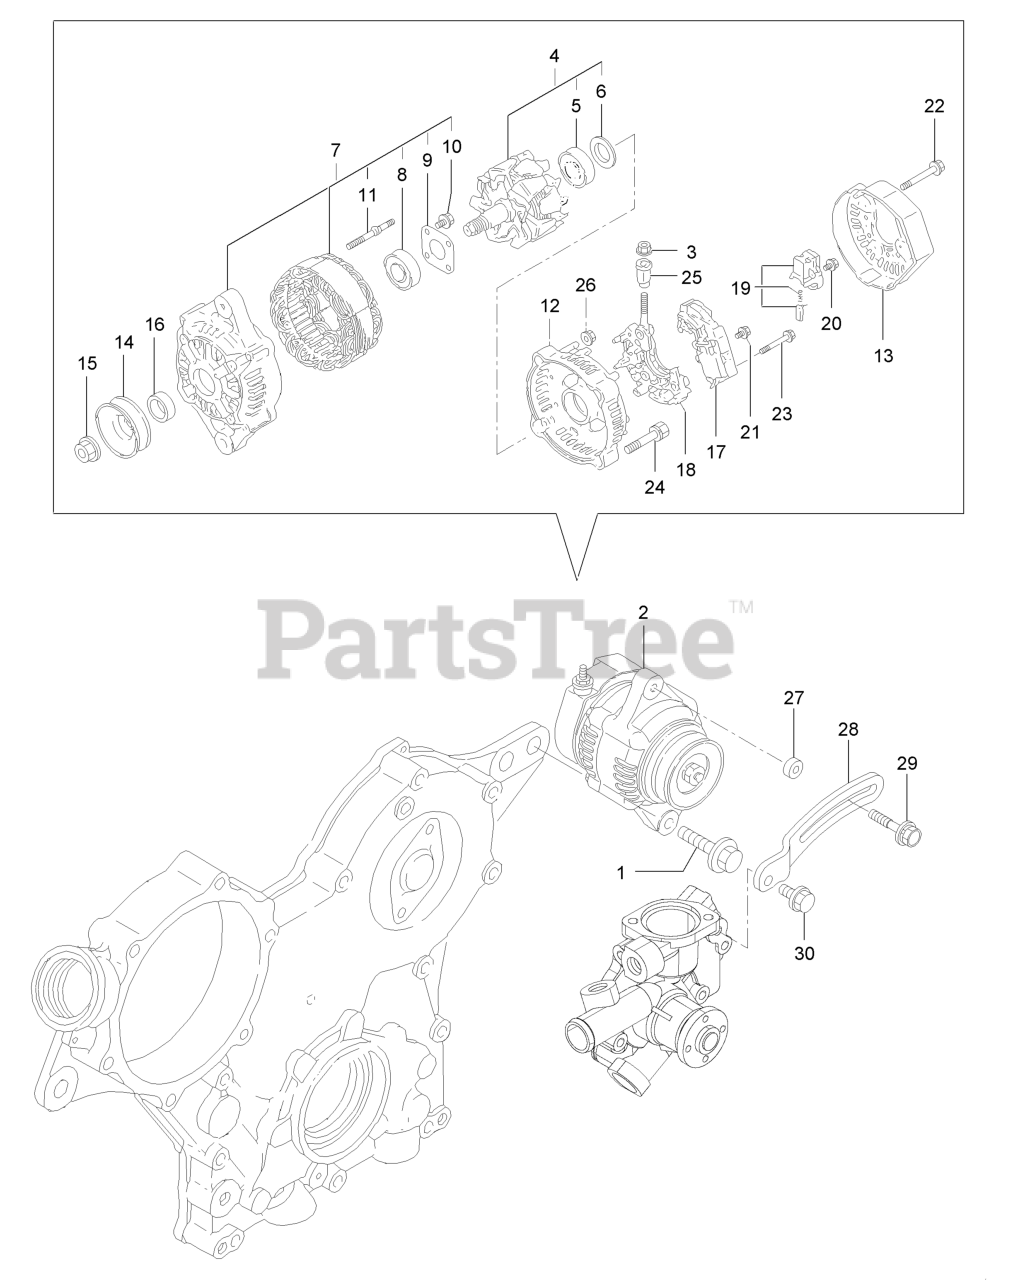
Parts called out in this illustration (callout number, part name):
2	Alternator
4	Rotor ASM
5	Bearing-Ball
7	Frame ASM
8	Bearing-Ball
9	Plate-Retainer
17	Regulator ASM
25	Bushing-Insulation
28	Adjuster-Belt
